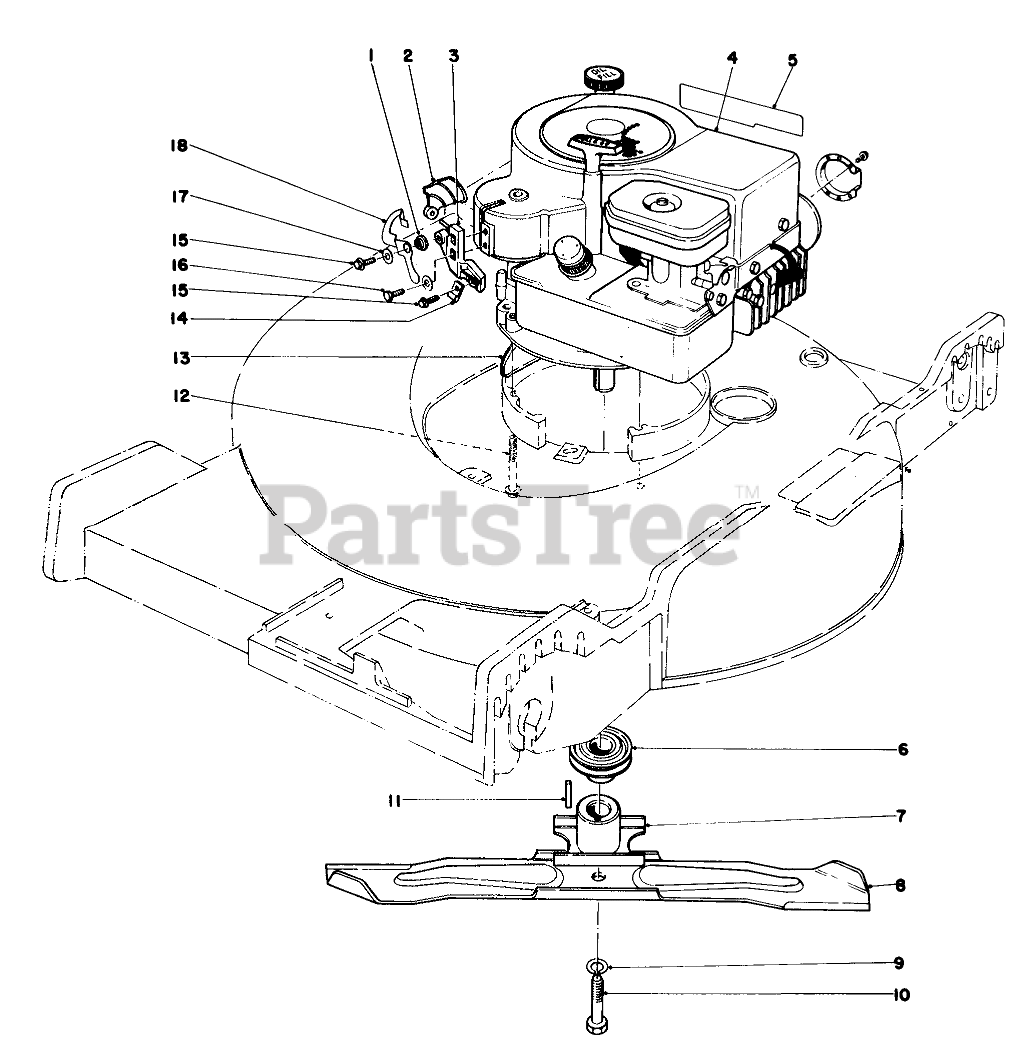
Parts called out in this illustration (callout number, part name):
1	BUSHING
2	INTERLOCK LEVER
3	CABLE & PIVOT BLOCK
4	Engine
5	Decal-Maintenance
6	DRIVER PULLEY
7	BLADE RETAINER WA(BLACK)
8	Blade
9	WASHER-LOCK
10	BLADE SCREW
11	KEY-SQUARE
12	3/8-16 X 2-3/4 CAPSCR
13	HOUSING CAP
14	CLAMP
15	SCREW-HWHTF
16	SCREW-SHWH
17	WASHER-FLAT
18	CAM INTERLOCK
